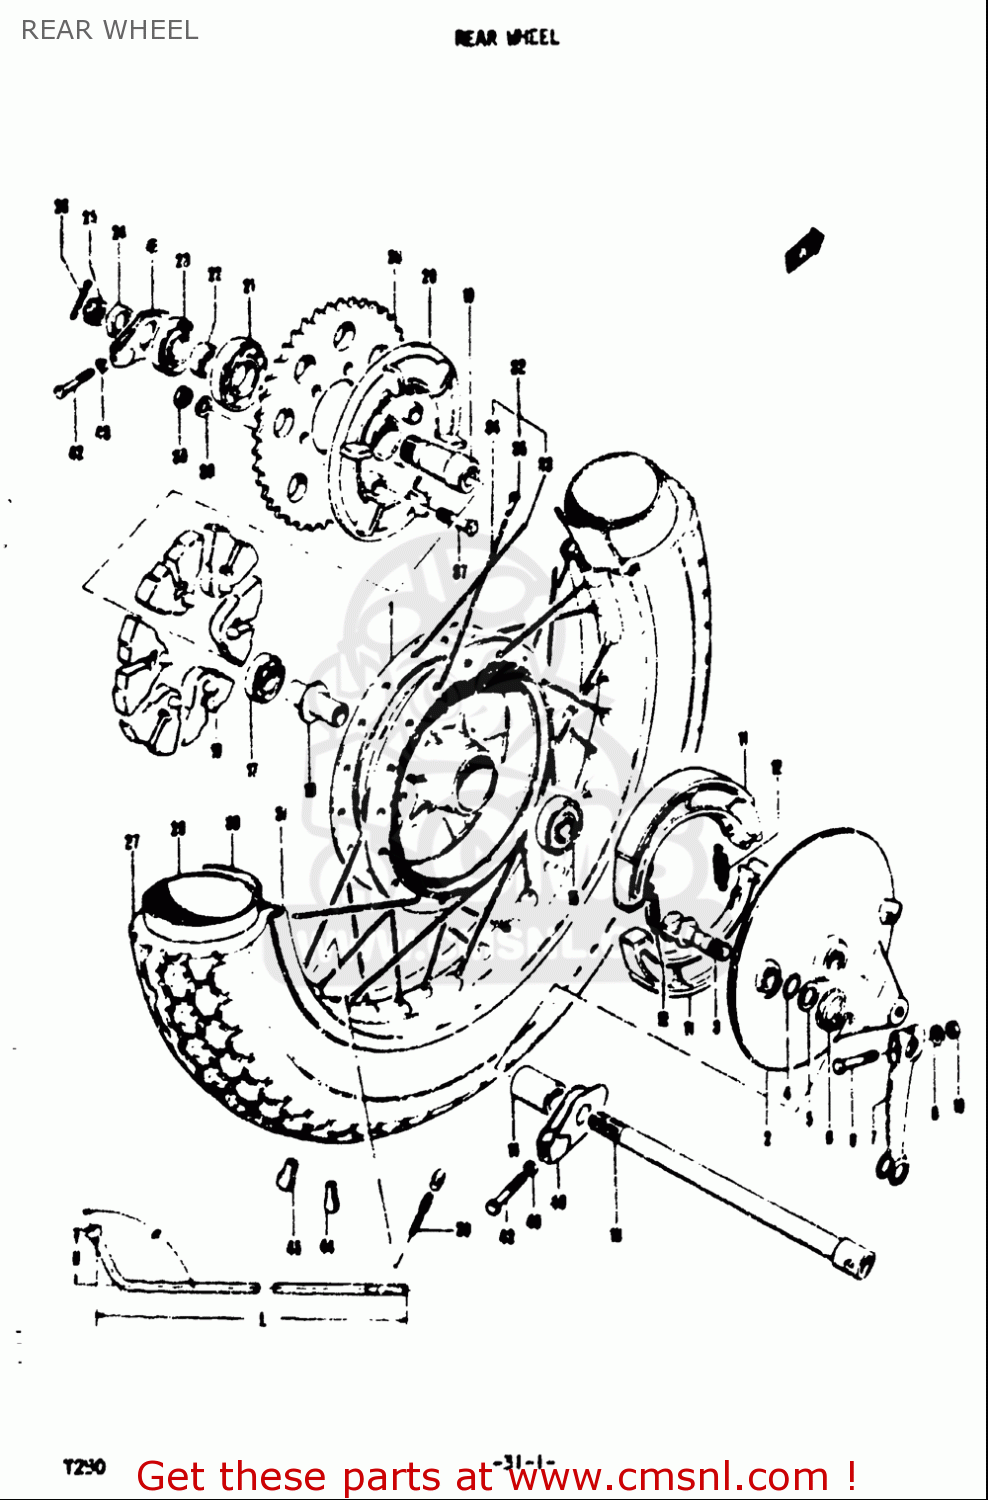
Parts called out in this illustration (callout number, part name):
4	O RING(D:2.4,ID:14.8)
5	WASHER(15.5X24X1.6)
6	SPRING
9	WASHER
10	NUT
11	SHOE SET,BRAKE (NAS)
12	SPRING,BRAKE SHOE
13	AXLE,REAR
15	BEARING
16	SPACER
17	BEARING
18	ABSORBER,RR HUB SHOCK
21	BEARING(25X52X15)
22	SPACER (25X30.5X11.3)
23	SEAL,OIL(30.5X52X8)
24	NUT
28	TUBE ASSY,INNER
30	PROTECTOR,INNER TUBE
31	RIM,RR WHEEL
32	SPOKE SET,RR WHEEL
37	BOLT(10X35.5)
38	WASHER
39	NUT
41	ADJUSTER,CHAIN,L
42	BOLT(8X50)
43	NUT
44	BALANCER,WHEEL (B)
45	BALANCER,WHEEL (30G)
